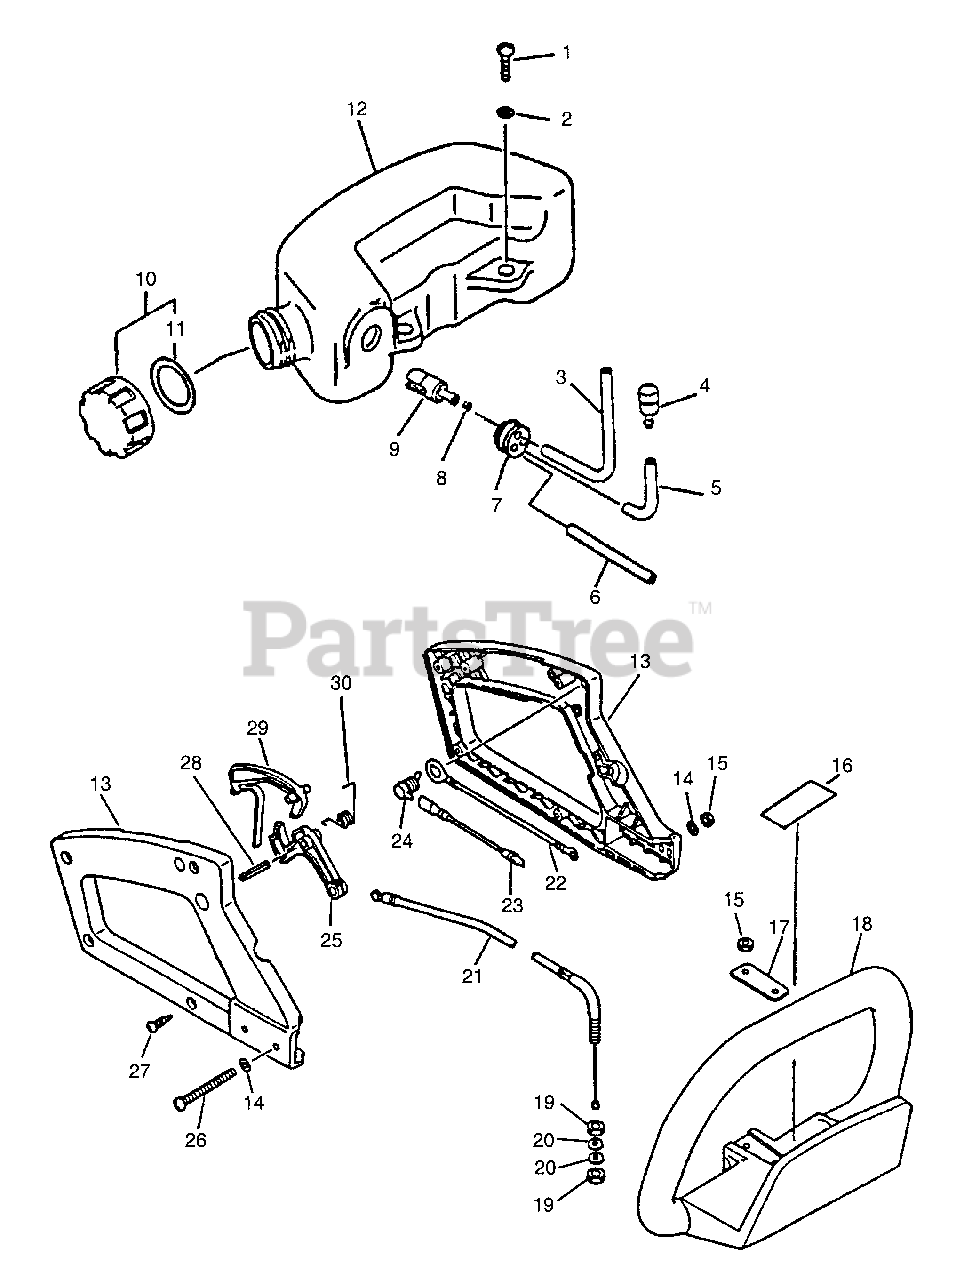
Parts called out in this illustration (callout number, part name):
1	SCREW 5×16
2	WASHER 5.5×12×0.8
3	PIPE, FUEL
4	VENT ASSY
5	PIPE, FUEL RETURN 3×6×70
6	PIPE, FUEL RETURN 3×6×110
7	GROMMET, FUEL
8	CLIP 6 MM
9	FILTER, FUEL
10	CAP ASSY, FUEL
11	GASKET, FUEL CAP
12	TANK, FUEL
13	HANDLE SET, REAR
14	WASHER, FLAT 5.5×10×0.8
15	NUT, LOCK M5
16	LABEL - CAUTION
17	PLATE, EYE
18	HANDLE, SUPPORT
20	WASHER 6.5×11.5×0.8
21	CABLE, THROTTLE
22	LEAD - GROUND
23	LEAD - GROUND
24	SWITCH, ON-OFF
25	TRIGGER, THROTTLE
26	SCREW 5×47
27	SCREW 4×16
28	PIN, SPRING Ø5×25 MM
29	LOCKOUT, THROTTLE
30	SPRING, THROTTLE RETURN
